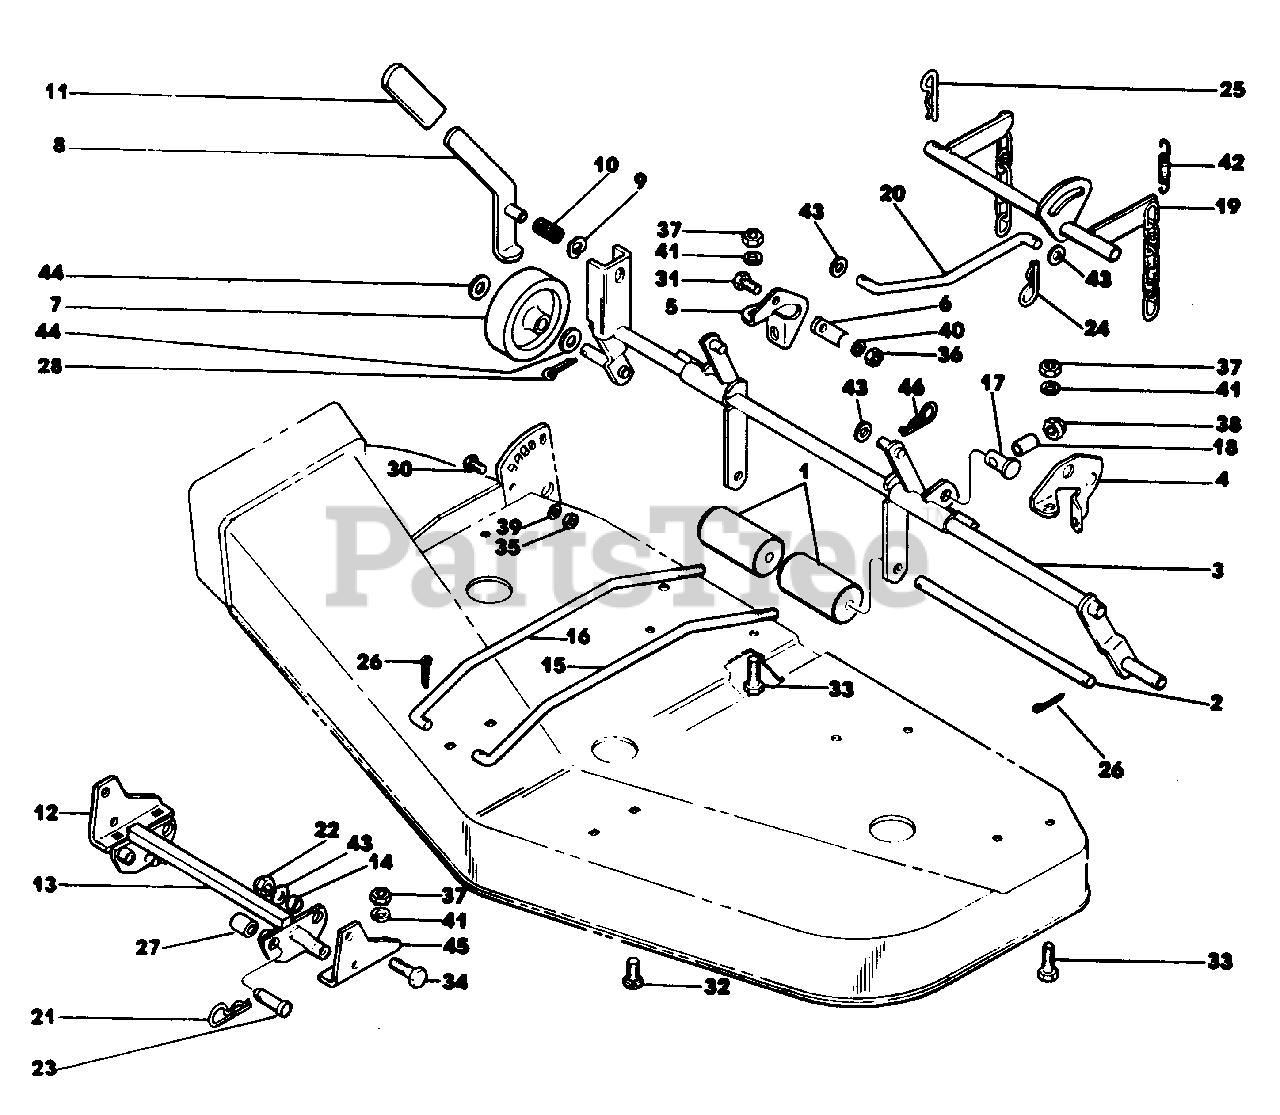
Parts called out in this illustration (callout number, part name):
1	Roller
2	Shaft Roller
3	Hanger Assembly, Wheel
4	Support, Wheel-L.H.
5	Support, Wheel, Center
6	Strap, Mid Support
7	Wheel, Mower
8	Handle Assembly, Height Adjustment
9	Washer, Wave
10	Spring
11	Grip
12	Bracket, Front Hanger-R.H.
13	Front Hanger Assembly
14	Bushing, Pivot
15	Rod, Level, R.H.
16	Rod, Level, L.H.
17	Pin, Pivot
18	Spacer
19	Bellcrank Assembly
20	Link, Mower Lift
21	Spring Clip
22	Nut, Hex Cone Lock 3/8-16 Plated
23	Pin, Clevis
24	Spring Clip
25	Spring Clip
26	Pin, Cotter 1/8 x 3/4 Plated
27	Spacer
28	Pin, Cotter 3/16 x 1" Plated
30	Cap Screw, Hex Hd. 1/4-20 x 1/2 Plated, Grade 5
31	Cap Screw, Hex 5/16-18 x 3/4 Plated, Grade 5
32	Bolt, Carriage Short Neck 3/8-16 x 3/4
33	Cap Screw, Hex Hd. 3/8-16 x 7/8 Plated, Grade 5
34	Cap Screw, Hex 3/8-16 x 1 1/8 Plated, Grade 5
35	Nut, Hex 1/4-20 Plated
36	Nut, Hex 5/16-18 Plated
37	Nut, Hex 3/8-16 Plated
38	Nut, Hex Cone Lock 1/2-13 Plated
39	Washer, Spring Lock 1/4 Plated
40	Washer, Spring Lock 5/16 Plated
41	Washer, Spring Lock 3/8 Plated
42	Lift Spring
43	Washer, Rat SAE 3/8 Plated
44	Washer, Flat SAE 5/8 Plated
45	Bracket, Front Hanger-L.H.
